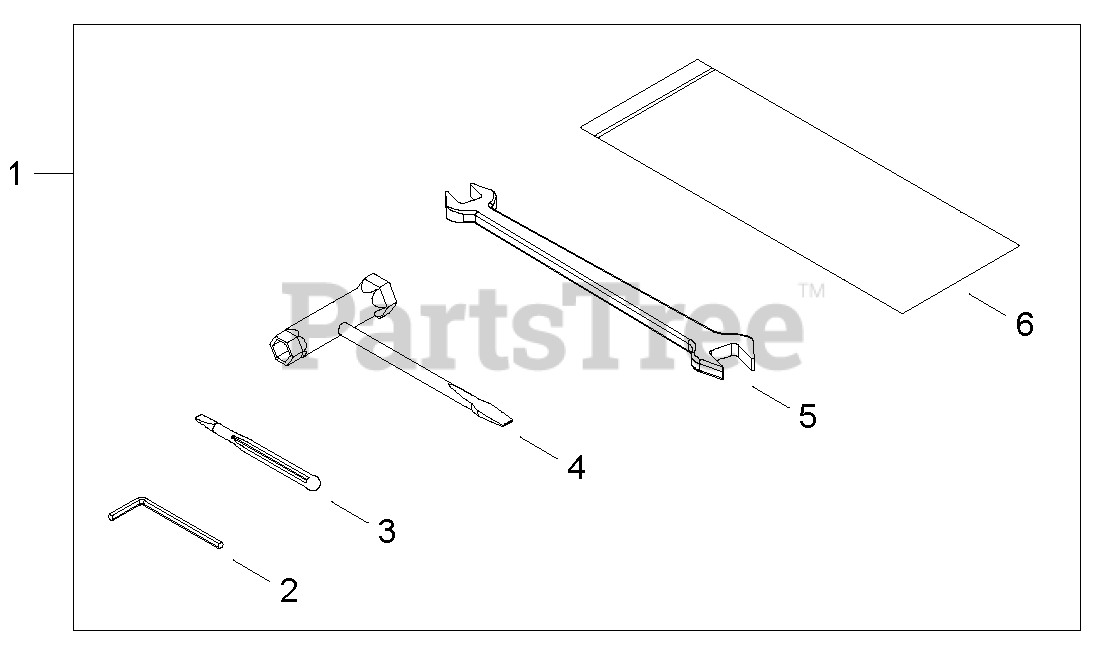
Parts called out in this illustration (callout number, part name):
2	WRENCH, ALLEN 4 MM
3	SCREWDRIVER, PLASTIC
4	T-WRENCH 13×19 MM
5	SPANNER 8×10
6	BAG, TOOL
14-1	TOOL KIT, SERVICE
